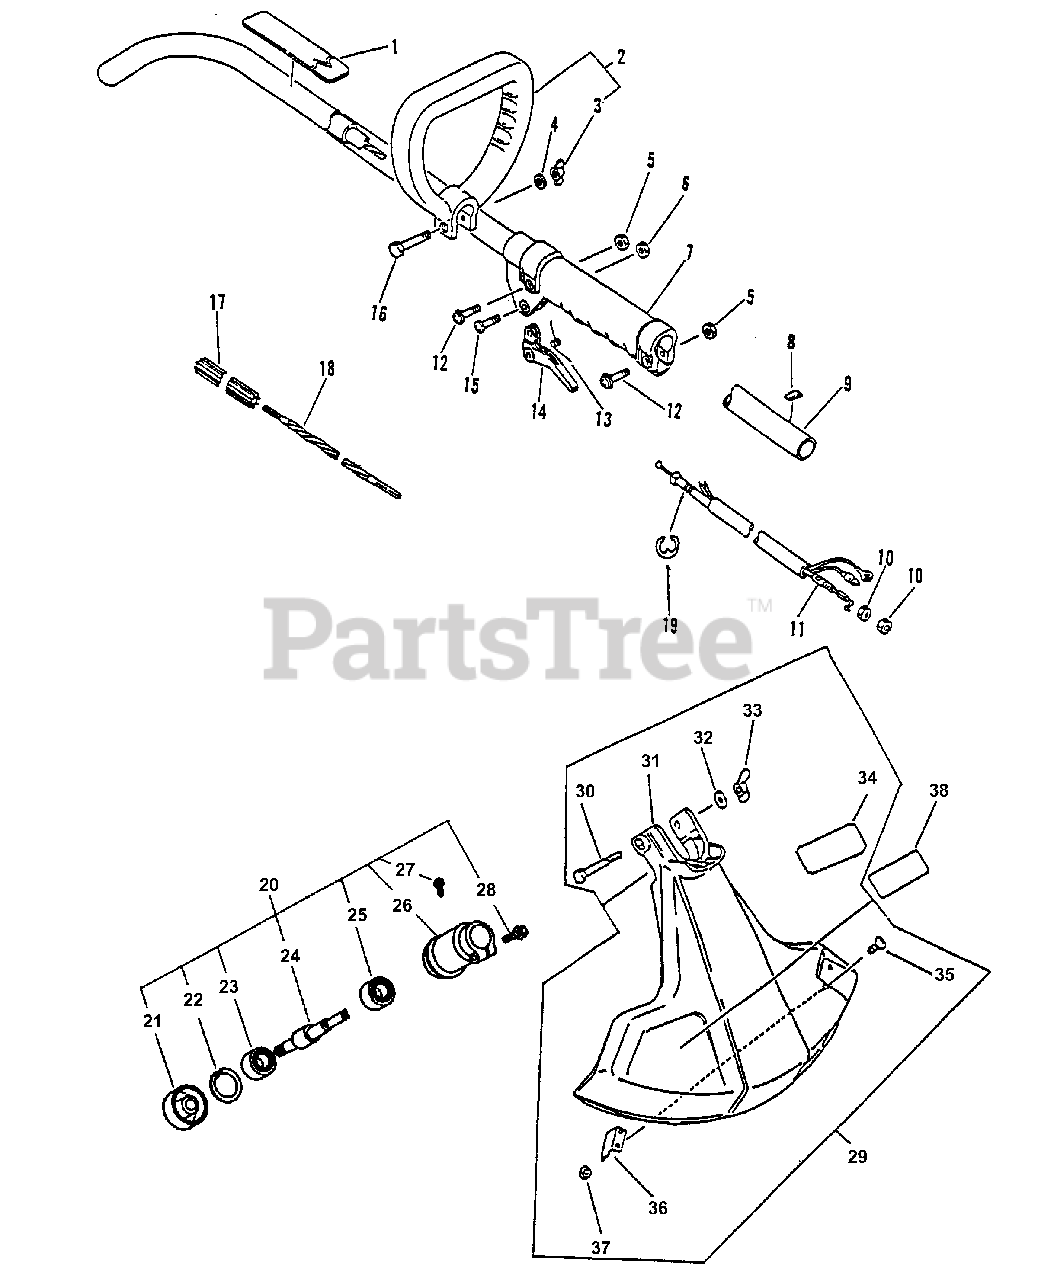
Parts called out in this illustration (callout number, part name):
1	LABEL - CAUTION
2	HANDLE ASSY
3	NUT - 1/4-20
4	WASHER - 1/4"
6	LOCKNUT - 5
7	GRIP, HANDLE
8	LABEL - ALIGNMENT
9	MAIN PIPE ASSY
11	CABLE, THROTTLE
12	SCREW - 5X25
13	SPRING, TRIGGER
14	TRIGGER, THROTTLE
15	SCREW - 5X30
16	BOLT - 1/4-20 X 1-1/2"
17	LINER - FLEXIBLE
18	DRIVESHAFT - FLEXIBLE
19	RING, RETAINING - 4
20	GEAR CASE ASSY
21	ADAPTOR, BLADE - UPPER
22	RING, RETAINING - 30
23	BEARING, BALL - 6200
24	GEAR - SHAFT
25	BEARING, BALL - 6200
26	CASE, GEAR
27	SCREW - 4X10
28	BOLT - 5X25
29	DEBRIS SHIELD KIT
30	BOLT - 1/4-20 X 2"
31	SHIELD, DEBRIS - PLASTIC
32	WASHER - 1/4"
33	NUT - 1/4-20
34	LABEL - CAUTION
35	SCREW - 5X16
36	KNIFE, TRIMMER LINE
38	LABEL - ECHO
